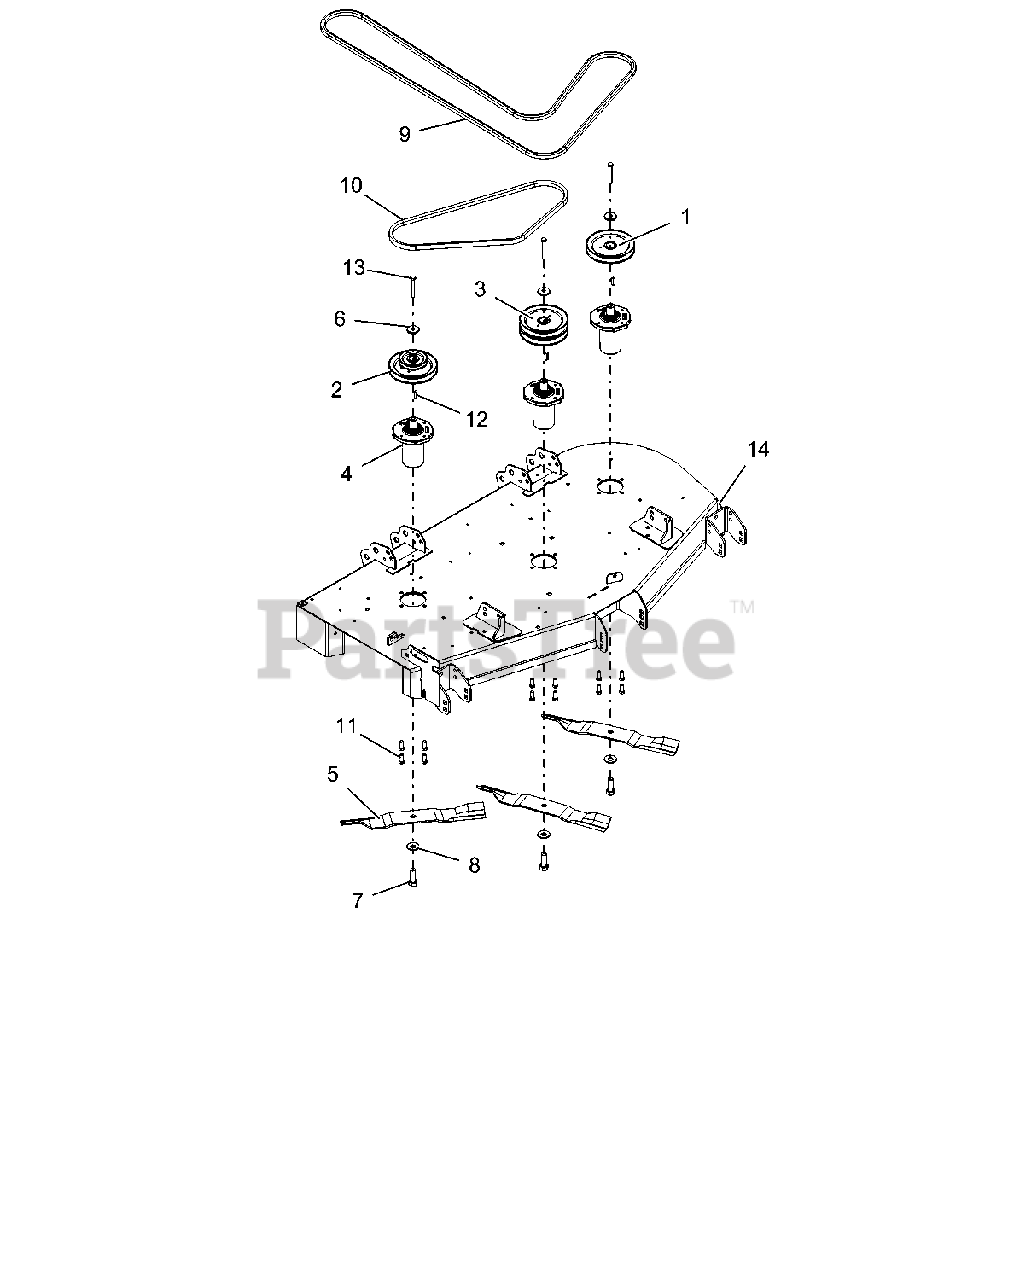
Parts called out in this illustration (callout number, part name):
1	PULLEY, SINGLE-1"ID X 6" OD
2	PULLEY, DOUBLE-1"IDX3.50"&6.0
3	PULLEY, DOUBLE
4	ASM, MAINT FREE SPINDLE
5	BLADE, 18"
6	RETAINER, SHEAVE
7	BLT-HEX .62-18X1.75 GR8 YWZC
8	WSHR-BLVL .669X1.535X.138
9	HEX BELT, BB-WRAPPED
10	V-BELT, B-COGGED
11	BLT-HEX .38-16X1.0 GR8 YZ EP30
12	KEY, SQ .25X.25X1.00 RC 40-50
13	BLT-HEX .38-16X2.75 GR8 YWZC
14	KIT,DECK - 52" W/SAFETY DECALS
